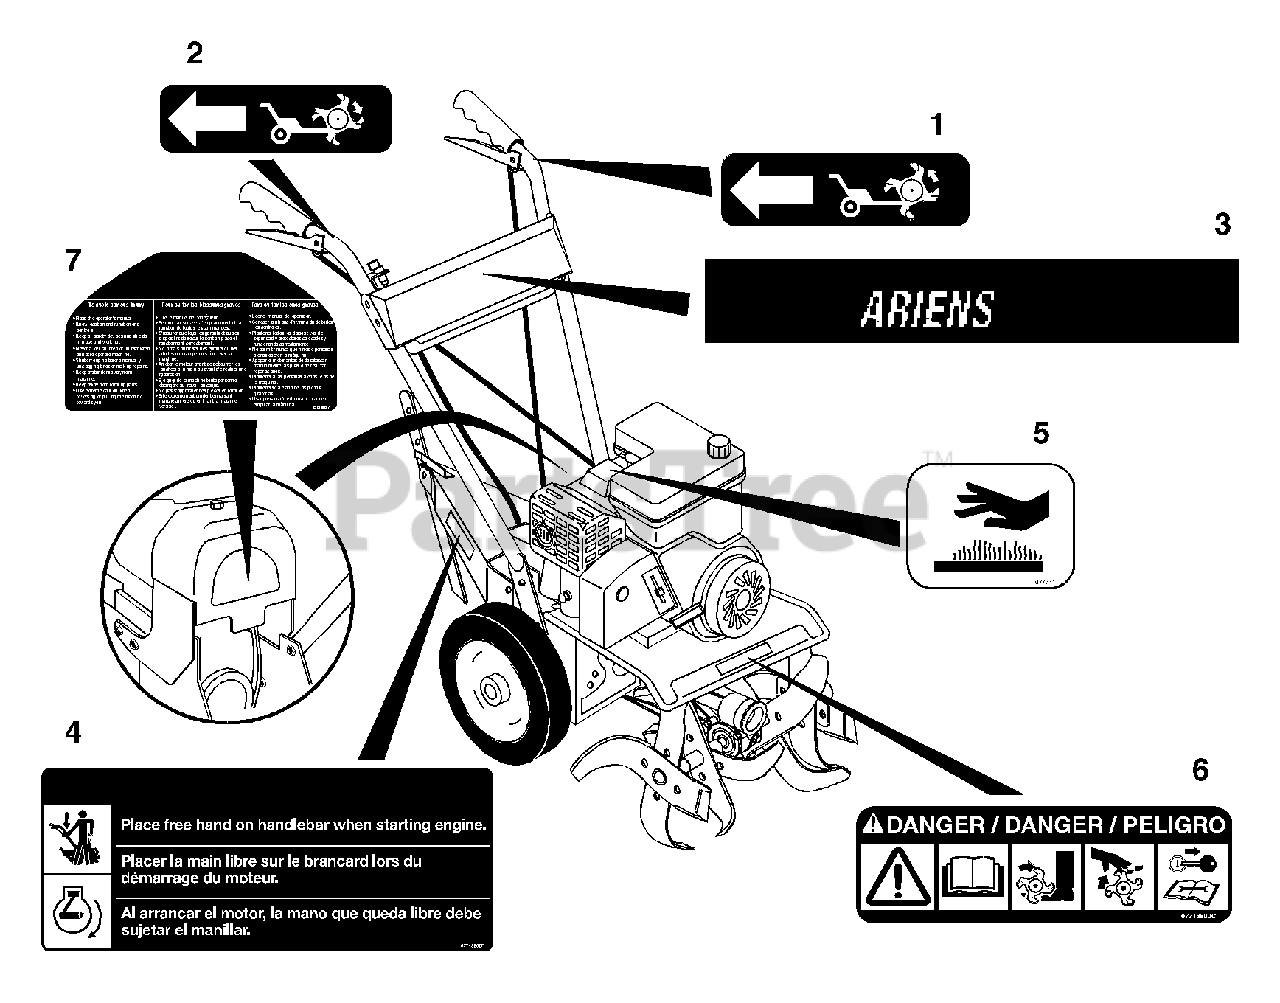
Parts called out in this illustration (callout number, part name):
1	DECAL-FORWARD
2	DECAL-REVERSE
3	DECAL, FT524 DASH
4	DECAL, CAUTION
5	DECAL, HOT SURFACE
6	DECAL, DANGER ROTATING TINES
7	DECAL, WARNING - BILINGUAL
